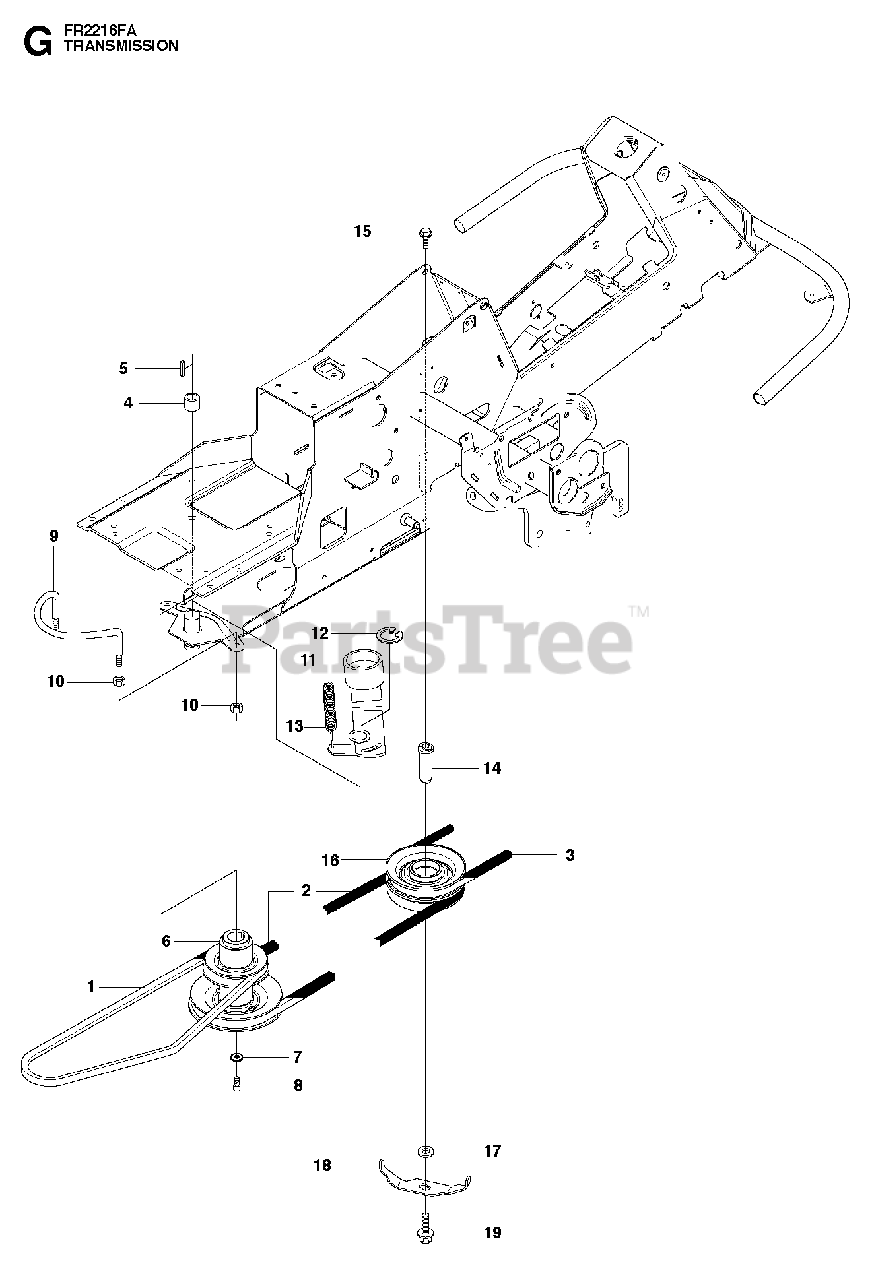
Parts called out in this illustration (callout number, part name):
1	BELT
2	BELT
3	BELT
9	BELT GUIDE
11	TENSIONER
12	RETAINING RING SGA 25
14	SHAFT
18	BELT GUIDE
19	BOLT
